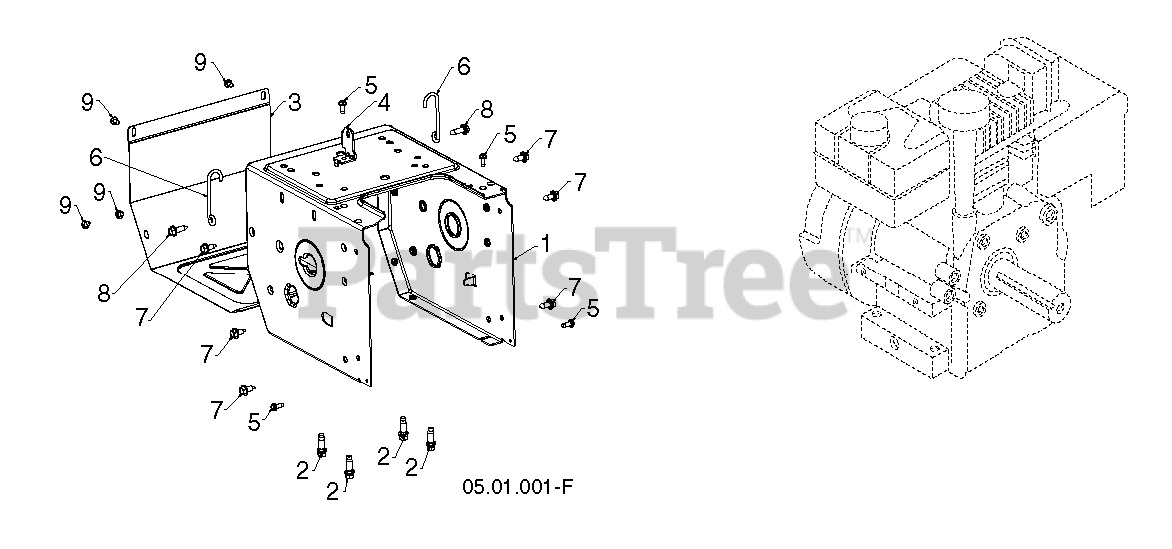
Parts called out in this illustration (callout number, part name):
1	FRAME.GEAR.CASE.ORANGE
2	BOLT 3/8-16X1-1/8
3	COVER COVER.FRAME MS668 ORANGE
4	BRACKET.SHIFTER.BZP
5	SCREW.HEX HEAD W/COLLAR 1/4-20
6	WIREFORM.SUPPORT.CABLE
7	BOLT.HEX.HD.WASHER.5/16-18X.75
8	SCREW HEX_SERR_HD_5_16-18X1.0
9	SCREW.HEX HEAD W/COLLAR 1/4-20
